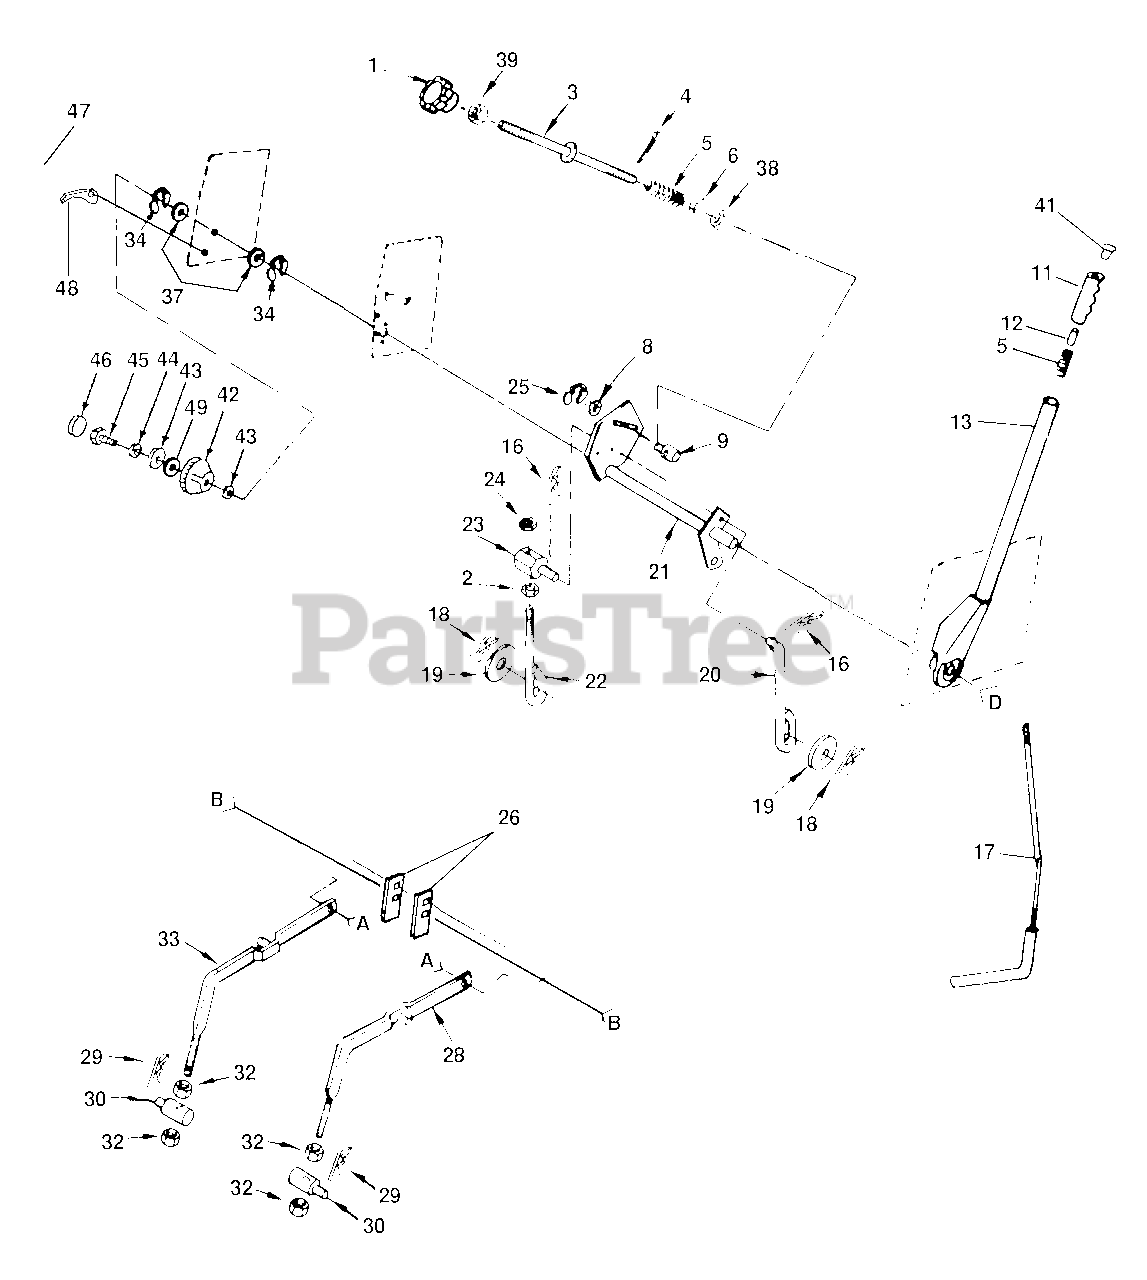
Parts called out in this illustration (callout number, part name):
1	Handle, Lift, Adjustment
2	Nut, Hex 3/8-16
3	Rod, Adjust, Lift
4	Pin, Cotter 3/32 x 1/2
5	Spring
6	Washer 13/32 x 5/8 x 16 Gauge
8	Washer 15/32 x 3/4 x 16 Gauge
9	Trunnion, Depth Stop
11	Grip, Handle
12	Plunger, Lever, Lift
13	Lever, Lift
16	Retainer, Spring
17	Rod, Lever
18	Retainer, Spring
19	Washer 17/32 x 15/16 x 16 Gauge
20	Link, Lift
21	Shaft, Lift, Assembly
22	Link, Lift, Adjust
23	Trunnion, Lift
24	Locknut 7/16-14
25	Ring, Klip
26	Upstop, Mower
28	Arm, Suspension, R.H.
29	Retainer, Spring
30	Trunnion, Lift, Lower
32	Nut, Hex, Fin. 1/2-13
33	Arm, Suspension, L.H.
34	E-Ring, Truarc
37	Washer 29/32 x 1-1/4 x 16 Gauge
38	Nut, Special
39	Nut, Hex, Jam 3/8 x 16 UNC
41	Button, Plunger
42	Scale, Height, Indicator
43	Washer 11/32 x 1-1/2 x 10 Gauge
44	Washer, Lock, Heavy, Helical, Spring
45	Bolt, Hex, Fin. 5/16-18 UNC x 1
46	Plug, Hole
47	Bolt
48	Pointer, Height Indicator
49	Washer, Nylon
